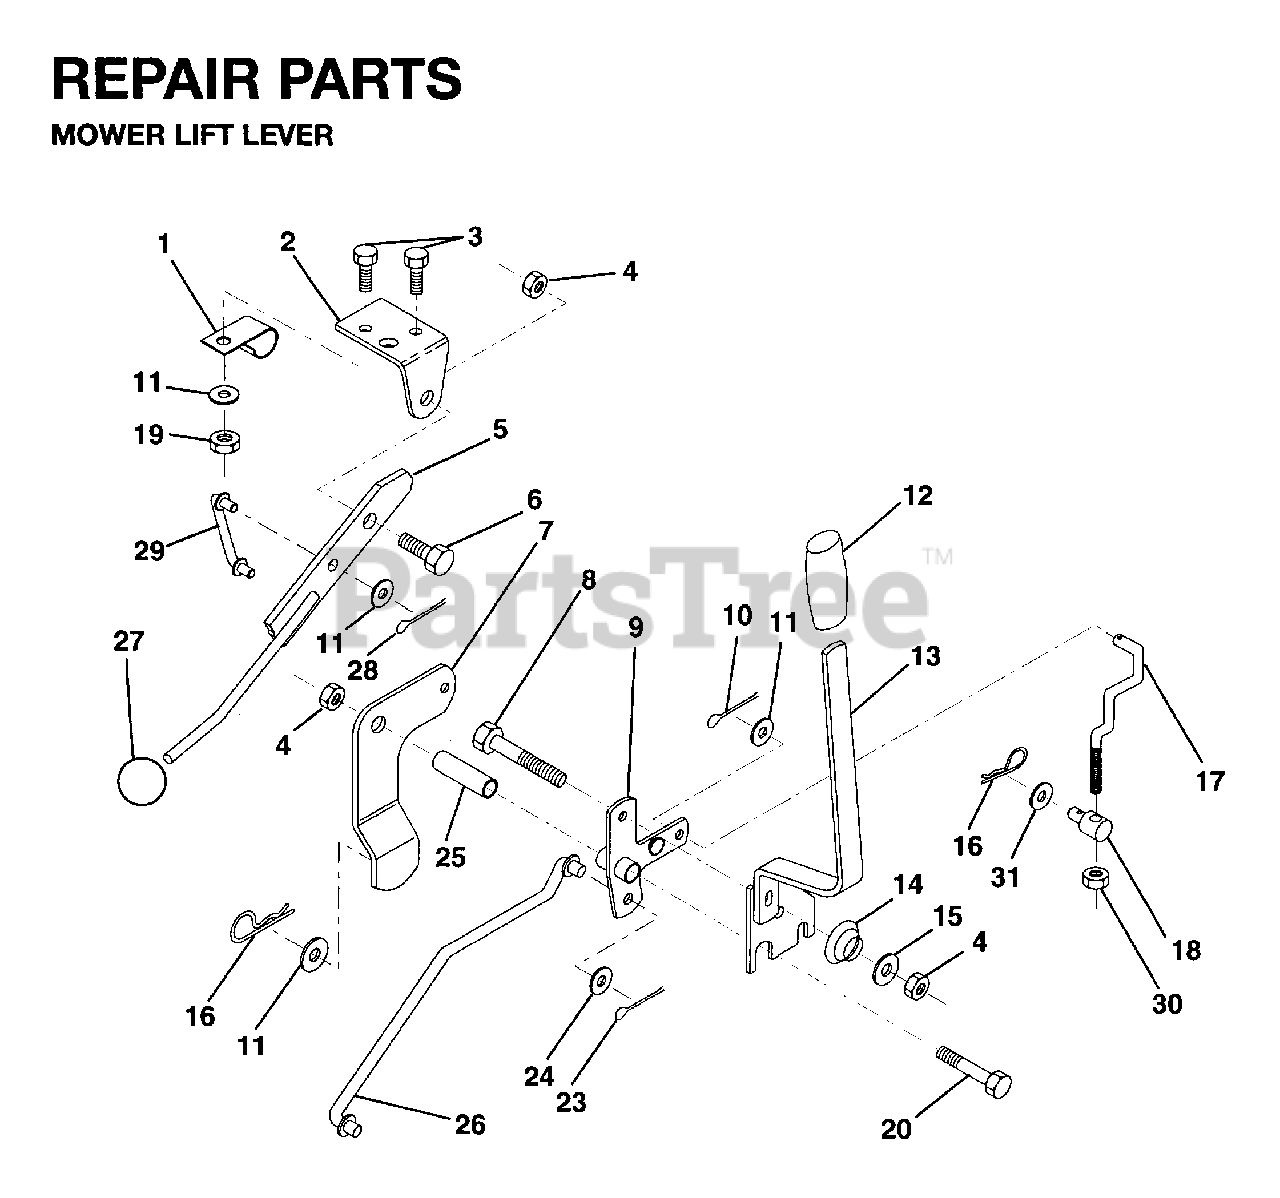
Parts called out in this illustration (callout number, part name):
1	CLIP,INSULATOR
2	BRKT CLUTCH
3	BOLT
4	LOCKNUT
5	CLUTCH LEVER
6	BOLT, SHOULDER LT
7	ASSEMBLY MOWER CLUTCH ARM
9	BELLCRANK,LIFT
10	COTTER PIN
11	WASHER
12	GRIP HANDLE
13	LIFT HANDLE ASSY
14	SPRING COMPRESSIO
15	WASHER
16	SPRING.RETAINER
17	LINK LIFT FRT
19	NUT.CROWNLOCK.1/4
23	PIN COTTER
24	WASHER - M12
25	TUBE SPACER
27	KNOB T (3/8 HOLE)
28	COTTER PIN
29	LINK MOWER CLUTCH
30	NUT.HEX.3/8-16UNC
